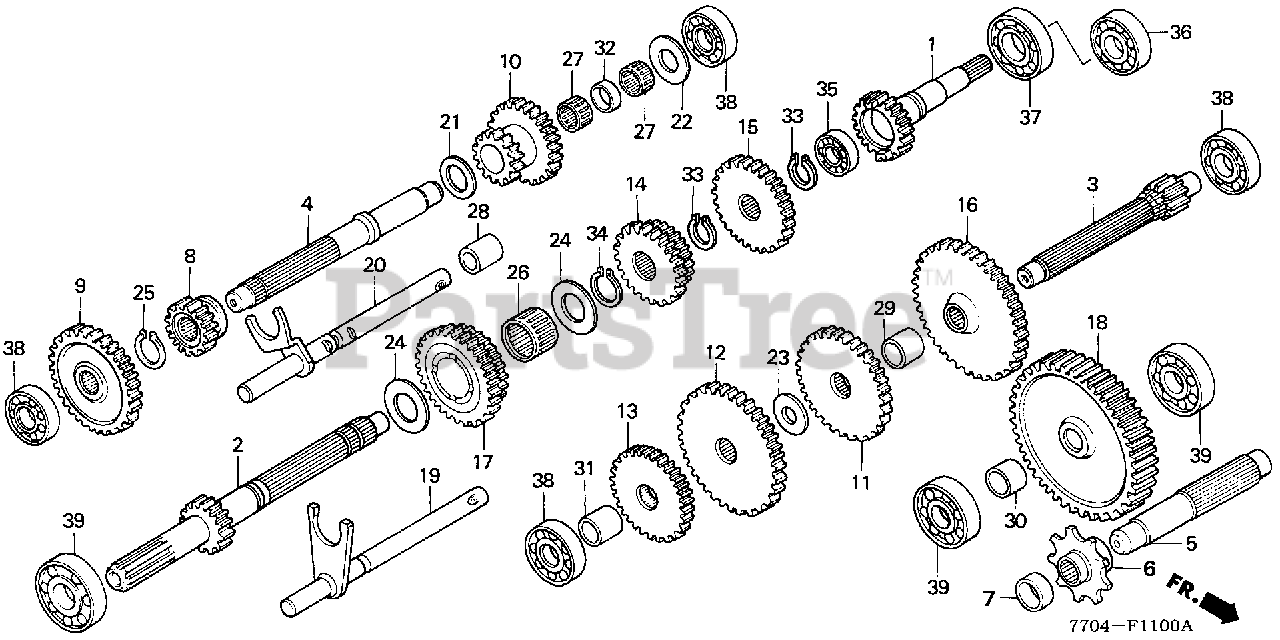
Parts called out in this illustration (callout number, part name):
1	SHAFT, INPUT (22T)
2	SHAFT, P.T.O.
3	COUNTERSHAFT (11T)
4	SHAFT, AUXILIARY
5	SHAFT, FINAL
6	SPROCKET, DRIVE (9T)
7	COLLAR A, FINAL SHAFT
8	GEAR, CHANGE (17T)
9	GEAR, REVERSE IDLE (34T)
10	GEAR, AUXILIARY IDLE (25T/17T)
11	GEAR, COUNTERSHAFT FIRST (33T)
12	GEAR, COUNTERSHAFT SECOND (39T)
13	GEAR, FIRST DRIVEN (36T)
14	GEAR, CHANGE (26T/15T)
15	GEAR, REDUCTION DRIVEN (30T)
16	GEAR, SECOND IDLE (45T)
17	GEAR, FIRST IDLE (23T/30T)
18	GEAR, FINAL (54T)
19	SHAFT, GEARSHIFT FORK (A)
20	SHAFT, GEARSHIFT FORK (B)
21	WASHER, THRUST (17.2MM)
22	WASHER, THRUST (15MM)
23	WASHER, THRUST (17.2X25)
24	WASHER, THRUST (20MM)
25	CIRCLIP, OUTER (17MM)
26	BEARING, NEEDLE (20X24X17)
27	BEARING, NEEDLE (17X21X13)
28	COLLAR, FORK SHAFT
29	COLLAR, COUNTERSHAFT (A)
30	COLLAR, FINAL SHAFT (20.8X25.4X11.0)
31	COLLAR, COUNTERSHAFT (B)
32	COLLAR, AUXILIARY IDLE GEAR
33	CIRCLIP, OUTER (18MM)
34	CIRCLIP (OUTER) (20MM)
35	BEARING, RADIAL BALL (6001SPL)
36	BEARING, RADIAL BALL (6003)
37	BEARING, RADIAL BALL (6004)
38	BEARING, RADIAL BALL (6202)
39	BEARING, RADIAL BALL (6203)
